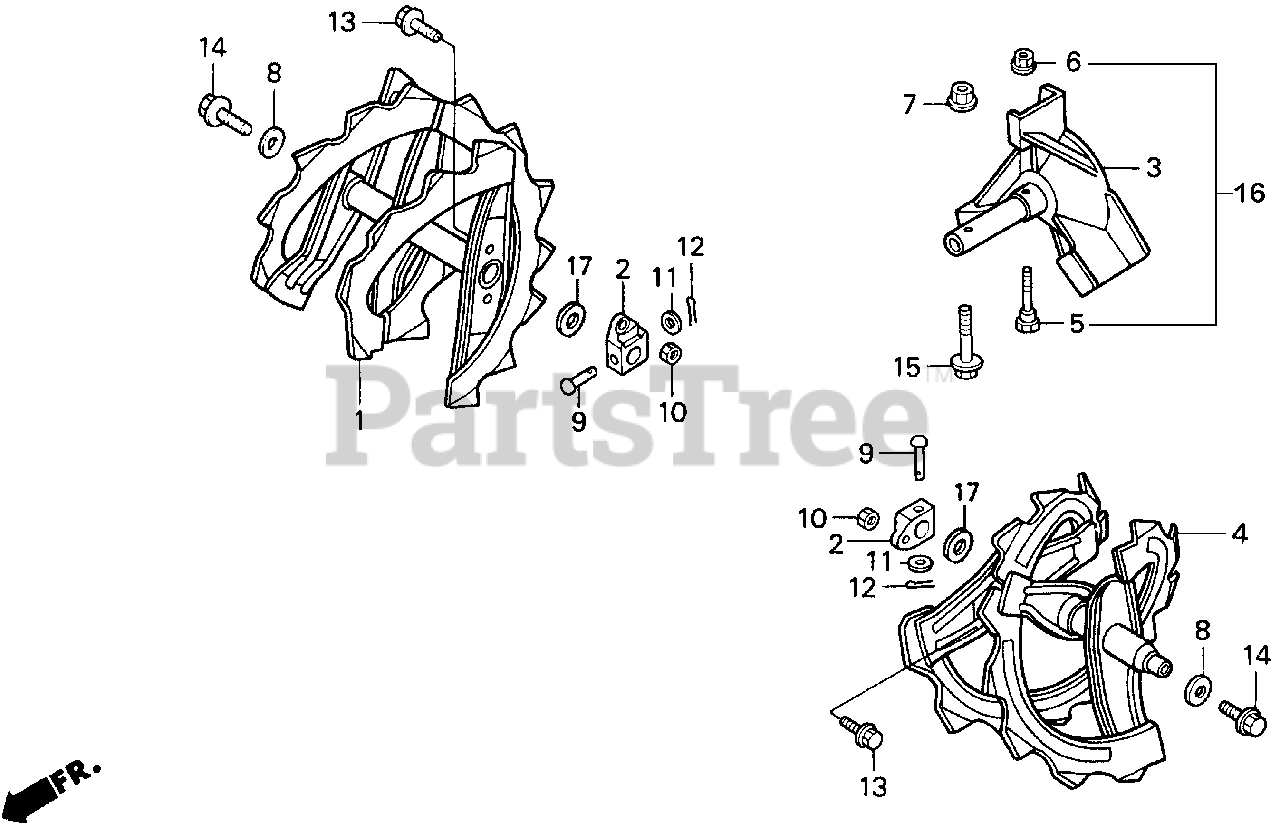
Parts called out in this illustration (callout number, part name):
2	BOSS, LOCK BOLT
5	BOLT, LOCK
6	NUT, SELF-LOCK (6MM)
7	NUT, FLANGE (M8X1.25) (SELF-LOCK)
8	WASHER (23X8.3X3.2)
9	PIN (7X40)
10	NUT, HEX. (6MM)
11	WASHER, PLAIN (7MM)
12	PIN, SPLIT (3.0X25)
12	PIN, SPLIT (3.0X45)
13	BOLT, FLANGE (6X16)
14	BOLT, FLANGE (8X16)
15	BOLT, FLANGE (8X35)
NI	AUGER SKID KIT, COMMERCIAL
